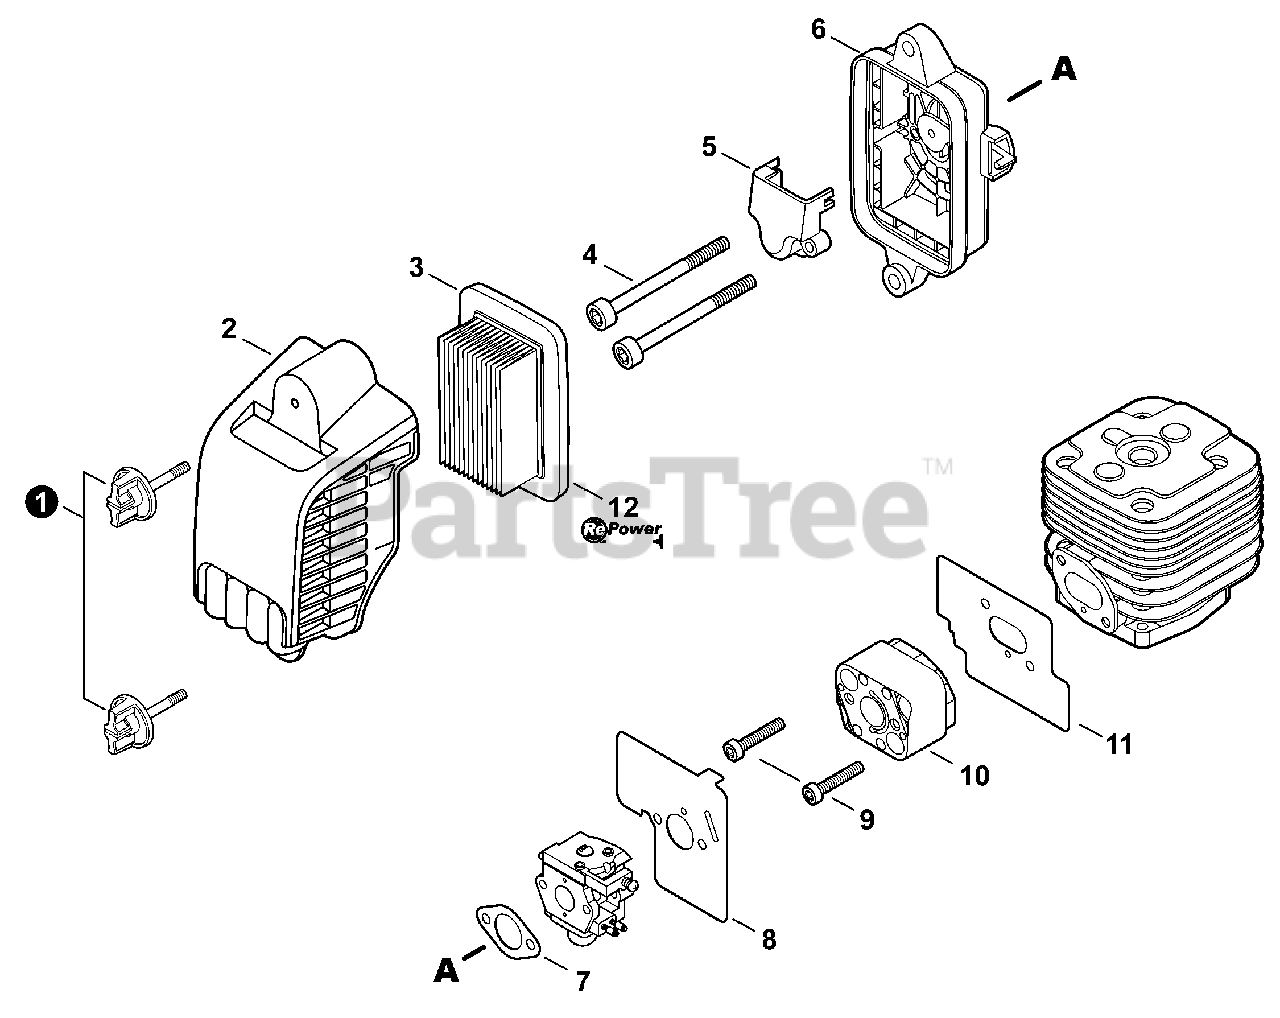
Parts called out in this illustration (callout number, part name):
1	KNOB, AIR FILTER COVER
2	COVER, AIR FILTER
3	FILTER, AIR
4	BOLT, TORX 5
5	PLATE, PREVENT
6	CASE, AIR FILTER
7	GASKET, INTAKE
8	GASKET, INTAKE
9	BOLT, TORX 5×25
10	INSULATOR, INTAKE
11	HEAT SHIELD, INTAKE
12	TUNE-UP KIT - REPOWER
